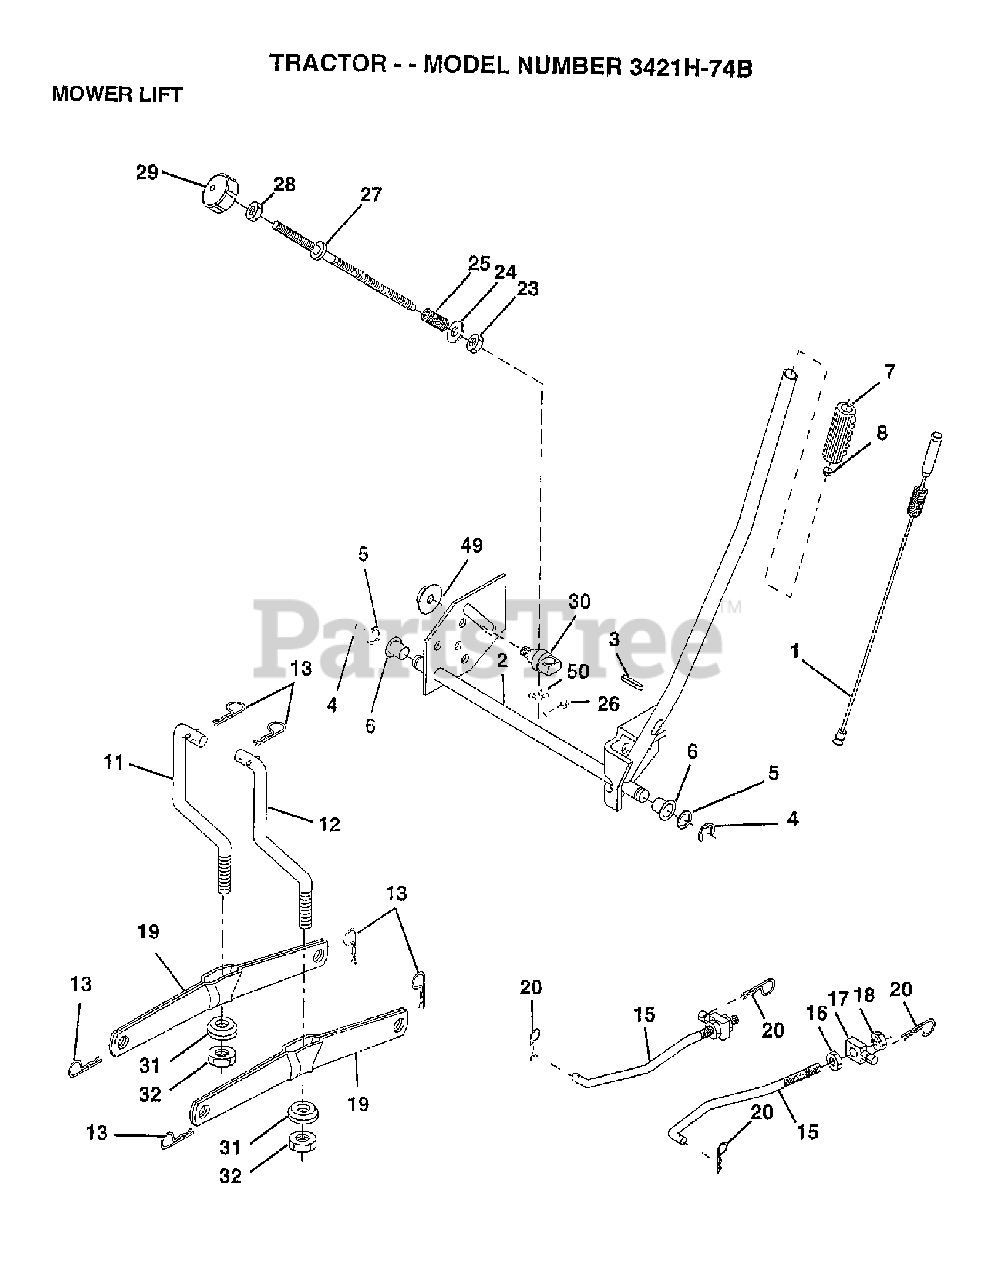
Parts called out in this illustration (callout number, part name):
1	WIRE.ASM.INNER.SP
2	SHAFT.ASM.LIFT.RH.INF
3	PIN GROOVE
4	RETAINING RING LT
6	BEARING.NYLON
7	GRIP
8	PLUNGER BUT KIT
11	LINK LIFT LH
12	Lift Link Assembly, RH
13	RETAINER SPRING
15	FRONT LINK
16	NUT.HEX.JAM.1/2-13
18	NUT.LK.W/WSH.1/2.
19	ARM.REAR.SUSPENSION
20	SPRING RETAINER
24	WASHER
25	SPRING.COMP.INF.H
27	ROD.LIFT.ADJUSTABLE
28	NUT
29	KNOB INF 3/8-16
30	TRUNNION
32	NUT CROWNLOCK 3/8-24
49	Flange Hex Lock Nut, 3/8-16
50	NUT PUSH M
